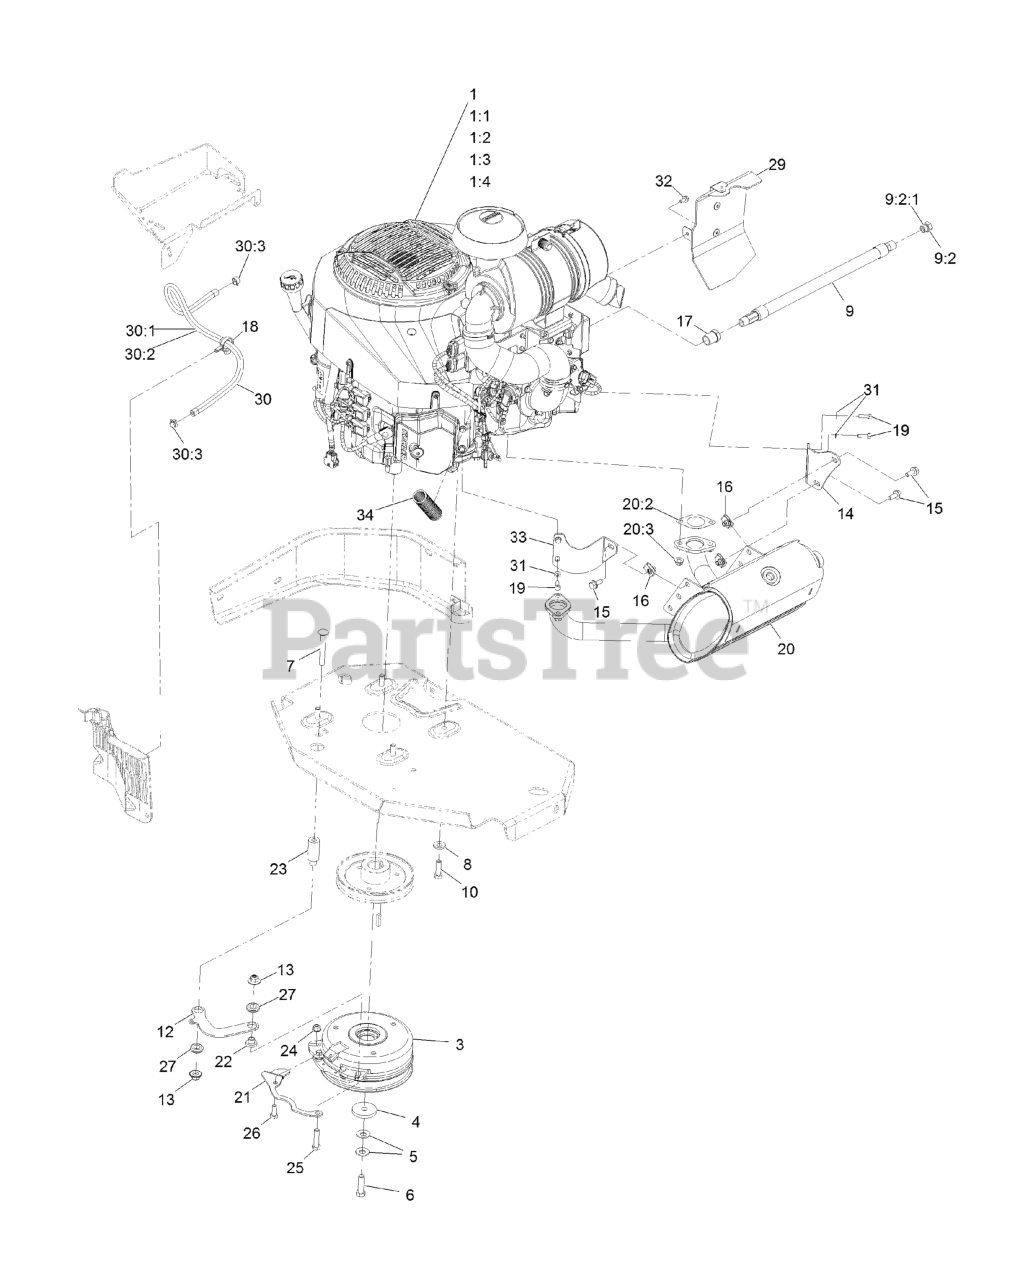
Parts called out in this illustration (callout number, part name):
1:1	Kohler 52 050 02-S Engine Oil Filter
1:2	Kohler 25 083 01-S Engine Air Filter
1:3	Kohler 25 083 04-S Safety Filter
1:4	Kohler 25 050 42-S Fuel Filter
3	CLUTCH KIT
4	WASHER-CLUTCH
5	WASHER-SPRING
6	SCREW-HH 7/16-20 X 1 1/2 W/LOCTITE
7	SCREW-CARR
8	WASHER-BELLEVILLE
9	OIL DRAIN HOSE ASM
9:2	PLUG-HH
9:2:1	O-RING
10	SCREW-HH
12	LINK-ANCHOR, CLUTCH
13	Nut-Nyloc 3/8-16 Flg
14	BRACKET-MUFFLER
15	SCREW-HHF
17	BUSHING
18	CLAMP-HOSE
19	SCREW-HH M6-1 X 20Mm W/Patch
20	MUFFLER KIT
20:2	GASKET-EXHAUST
20:3	NUT-FLANGE, LOCK
21	BELT-GUIDE
24	NUT-HF, NI
25	SCREW-HH
26	SCREW-HH
27	GROMMET-RUBBER
29	REAR BAFFLE ASM
30	FUEL LINE ASM
30:1	HOSE-FUEL
30:2	SLEEVE, THERMAL
30:3	CLAMP-HOSE
31	WASHER-SPRING
32	SCREW-HWH
33	BRACKET-MUFFLER, FRONT
34	CONDUIT-CONVOLUTED
